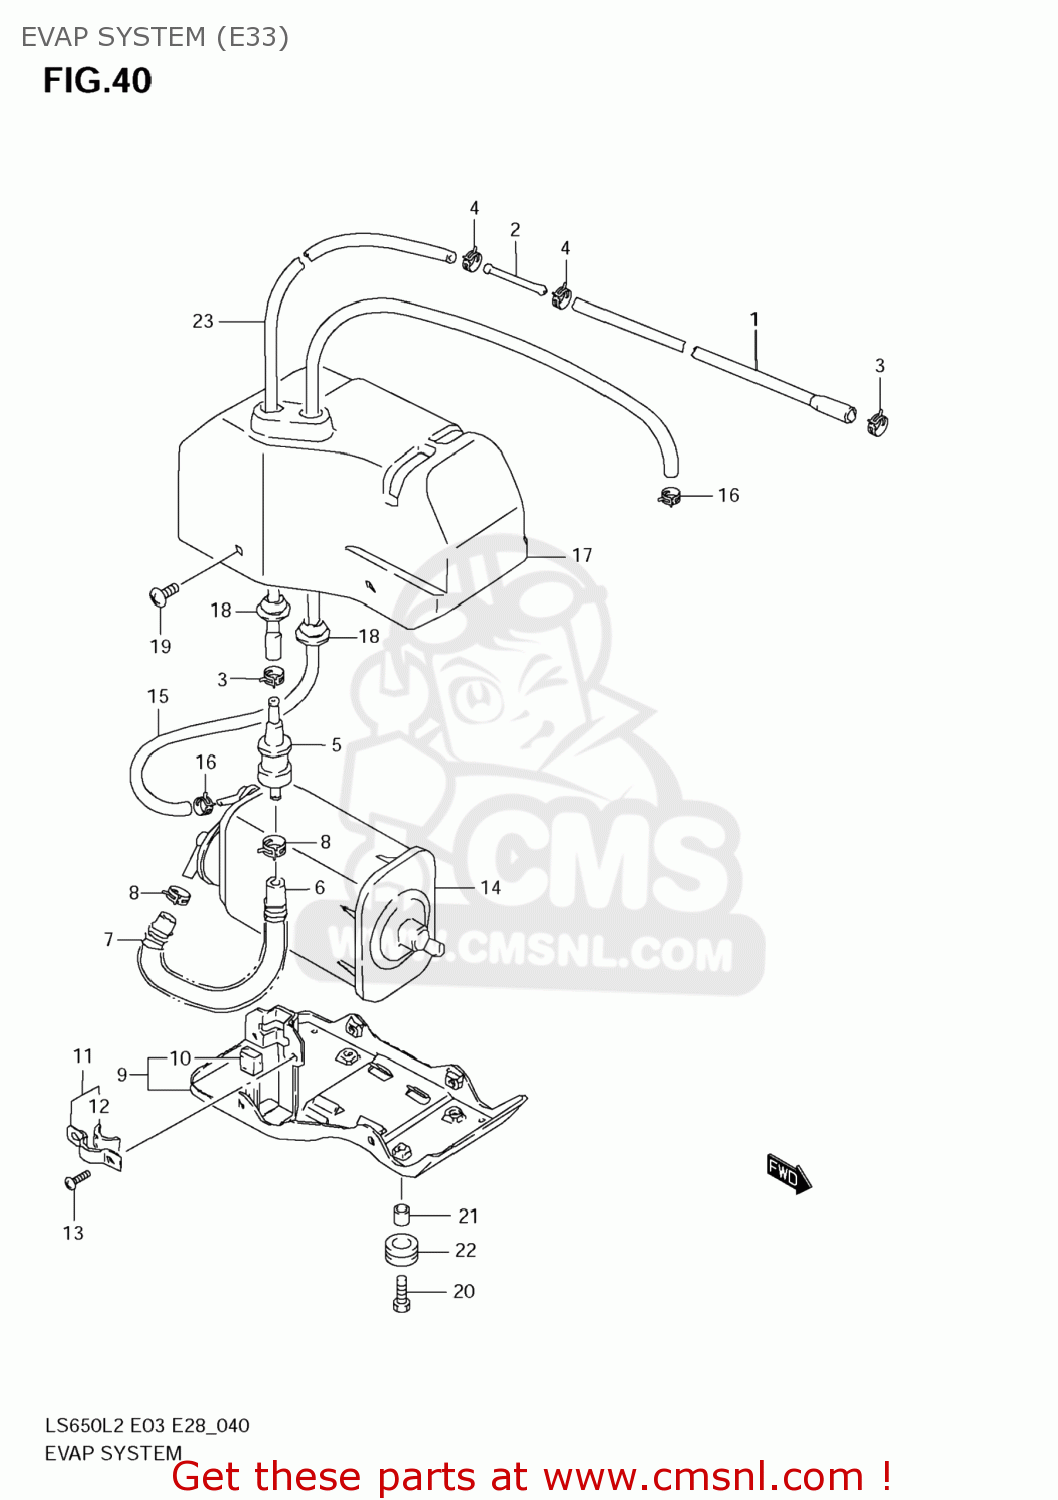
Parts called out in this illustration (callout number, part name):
1	HOSE,EVAP SYSTEM NO.3 CHG
2	JOINT
3	CLIP
4	CLIP
5	VALVE,FUEL TANK BREATHER
6	HOSE,EVAP SYSTEM NO.1
7	SPRING
8	CLIP
9	PLATE,CSTR FITING
10	CUSHION
11	PLATE,FUEL TANK BREATHER NO.2
12	CUSHION
13	SCREW
14	CANISTER ASSY,CHARCOAL
15	HOSE,EVAP SYSTEM NO.4 PURGE
16	CLIP
17	COVER,CANISTER
18	GROMMET
19	SCREW
20	BOLT(6X16)
21	SPACER(6.5X9X7.2)
22	CUSHION
23	HOSE,EVAP SYSTEM NO.2 CHG
